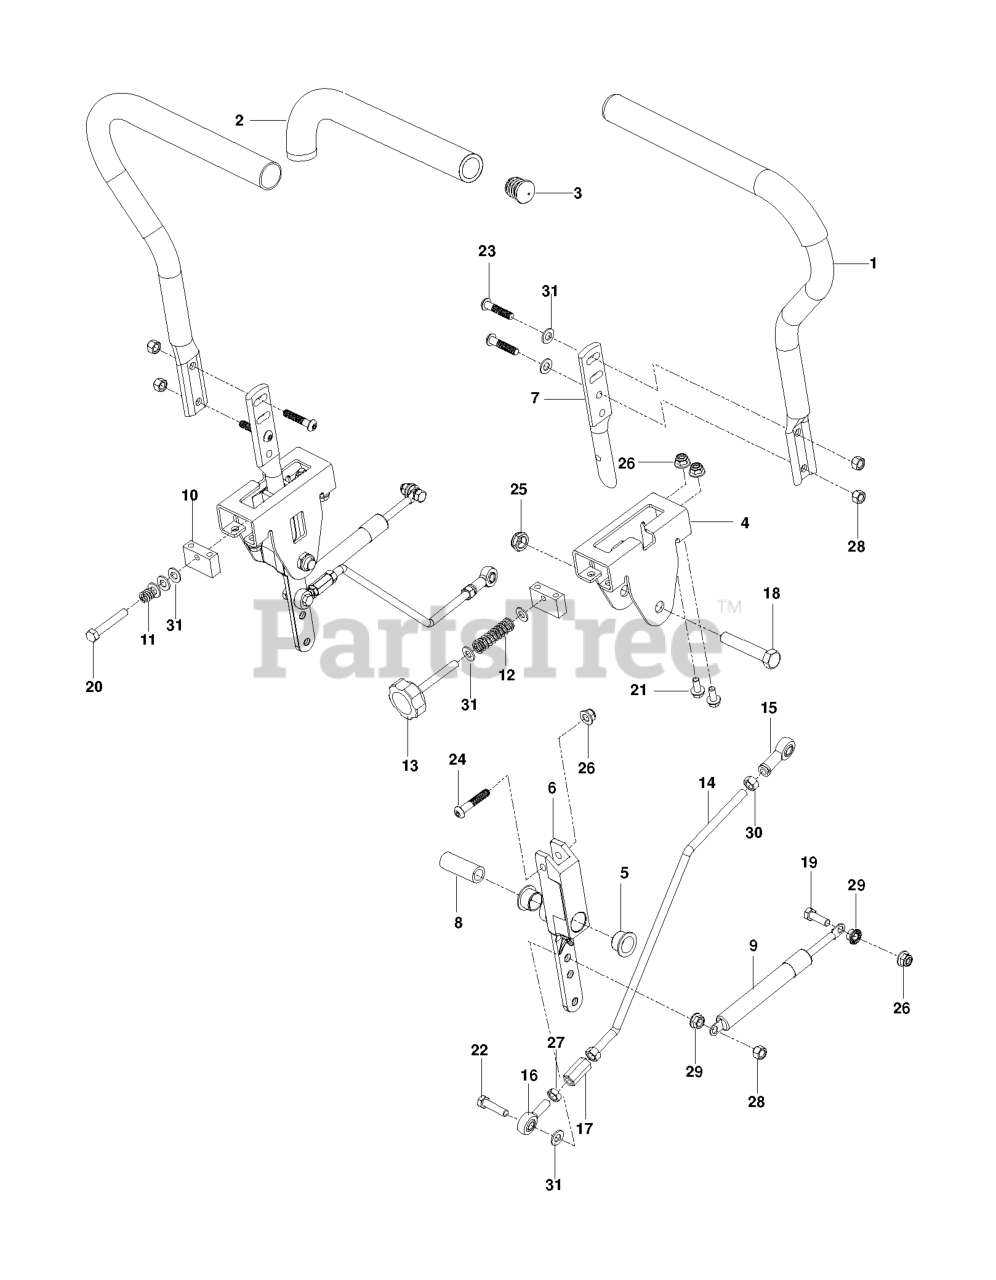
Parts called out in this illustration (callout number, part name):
1	LEVER ASSEMBLY
2	GRIP, FOAM (GROUND) 15
3	END PLUG 15/16 (BLACK)
4	BRACKET, CONTROL
5	BEARING, FLANGE
6	LEVER CONTROL PIVOT
7	LEVER.HANDLE MOUNT
8	SPACER, PIVOT CONTROL
10	BLOCK.TRACKING
12	SPRING COMPRESSION 2.0
13	KNOB
14	ROD, MOTION CONTROL
15	RH ROD END
16	RP.ROD.END.LH
17	ROD END COUPLER
18	HCS 1/2C X 2 3/4
19	HCS 5/16C X 1
20	CAPSCREW 5/16 X 1/1/2 HEX HEAD
21	HHFS 5/16-18 X 3/4
22	HCS 5/16C X 1 3/4
23	SCREW BUTTONHEAD 5/16-18X1-1/2
24	SCREW 5/16-18 X 1 3/4 BTN-HD
25	NUT 1/2-13 HEX JM NYL
26	5/16-18 NYLOC FLANGE NUT
27	NUT 5/16F LEFTHAND
28	NUT 5/16 NYLOC
29	NUT 5/16C WHIZ
31	FLAT WASHER 5/16 SAE
